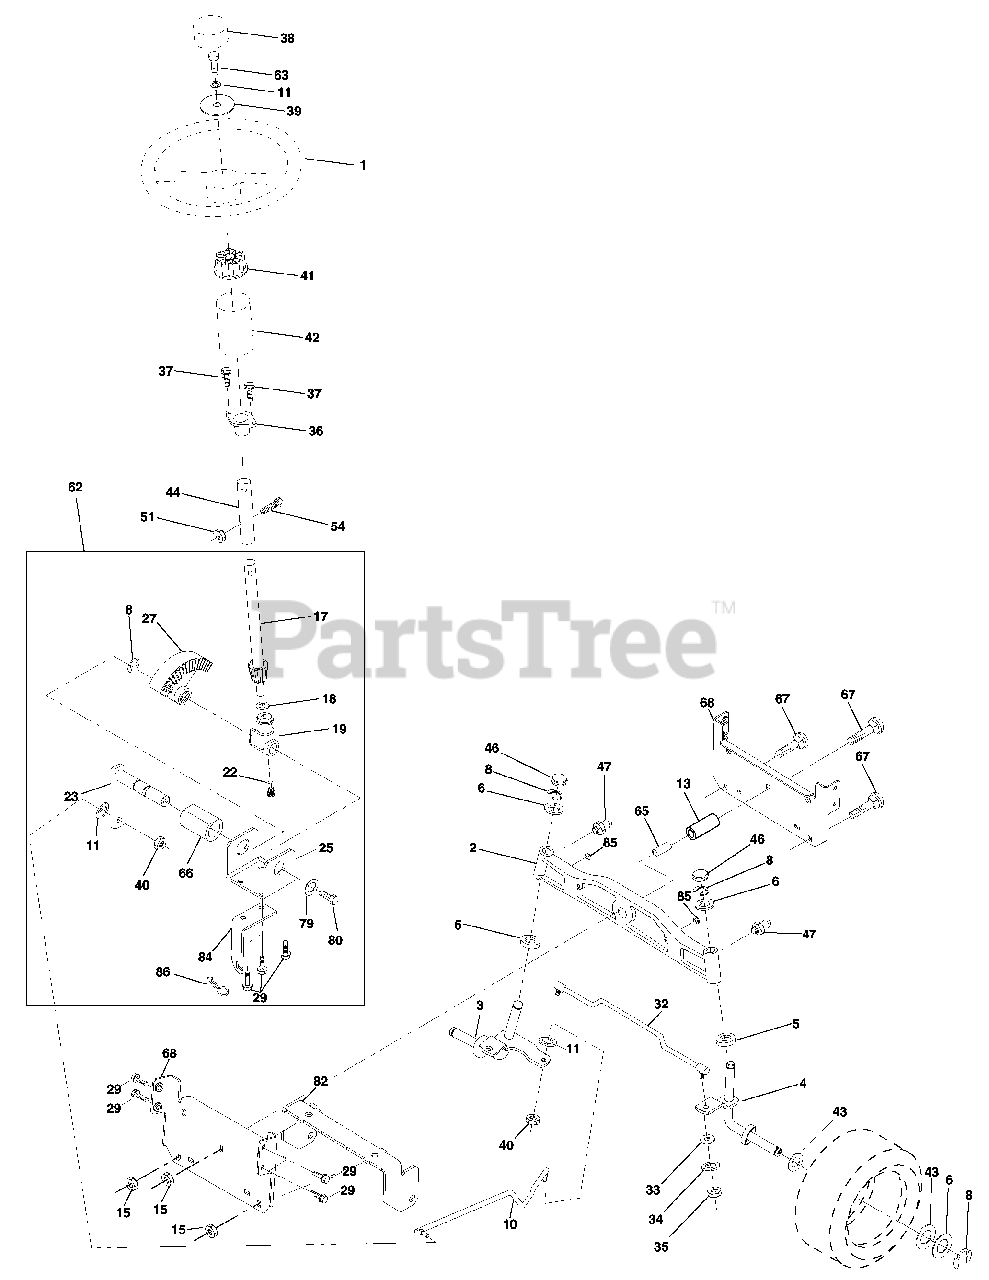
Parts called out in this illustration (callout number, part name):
1	Steering Wheel
2	Axle Cast Lt Machined
3	Spindle Assembly, L.H.
4	Spindle Assembly, R.H.
5	Bearing, Race, Thrust, Hardened
6	Washer 25/32 x 1-5/8 x 16 Gauge
8	Ring, Klip
10	Link, Drag
11	Washer, Lock
13	Spacer Brg Axle Front
15	Nut Hex Flange Lock
17	Shaft Assembly, Steering
18	Washer, Thrust .515 x .750 x .033
19	Support, Shaft
22	Screw Hex Wshhd Torx
23	Pittman Shaft Assembly
25	Bracket, Steering
27	Gear, Sector
29	Screw 3/8-16 x 3/4
33	Washer 11/32 x 3/4 x 16 Ga.
34	Washer Lock Hvy Hlcl Spr 5/16
35	Locknut 5/16-24 Unf
36	Bushing, Steering
37	Screw TT #10-32 x 5 x 3/8 Flange
38	Cap Wheel Steering
39	Washer 13/32 x 1-1/20 x 11 Gauge
40	Nut Lock Center 3/8-24 Unf
41	Adaptor, Steering Wheel
42	Boot, Steering Dash P/L Mtl
43	Washer 25/32 x 1-1/4 x 16 Gauge
44	Extension Steering Non-Adjust
46	Cap, Spindle
47	Fitting, Grease
51	Nut Lock Hx W/Ins 5/16-18 UNC
54	Bolt Fin Hex 5/16-18 UNC x 1-1/4
62	Kit, Steering Assembly, Service
63	Bolt Fin Hex 3/8-16 unc. x 1 Gr. 5
65	Spacer Brace Axle
66	Bearing Arm Pittman
67	Bolt Rdhd Sq 3/8-16 x 2-1/4
68	Brace Axle
79	Washer 13/32 x 1-1/4 x 12 Ga
80	Bolt Hex Nylon 3/8-16 x 3/4
82	Bracket Susp Chassis Front
84	Bracket Cable Clutch Chassis
85	Fastner Christmas Tree
86	Retainer Spring
